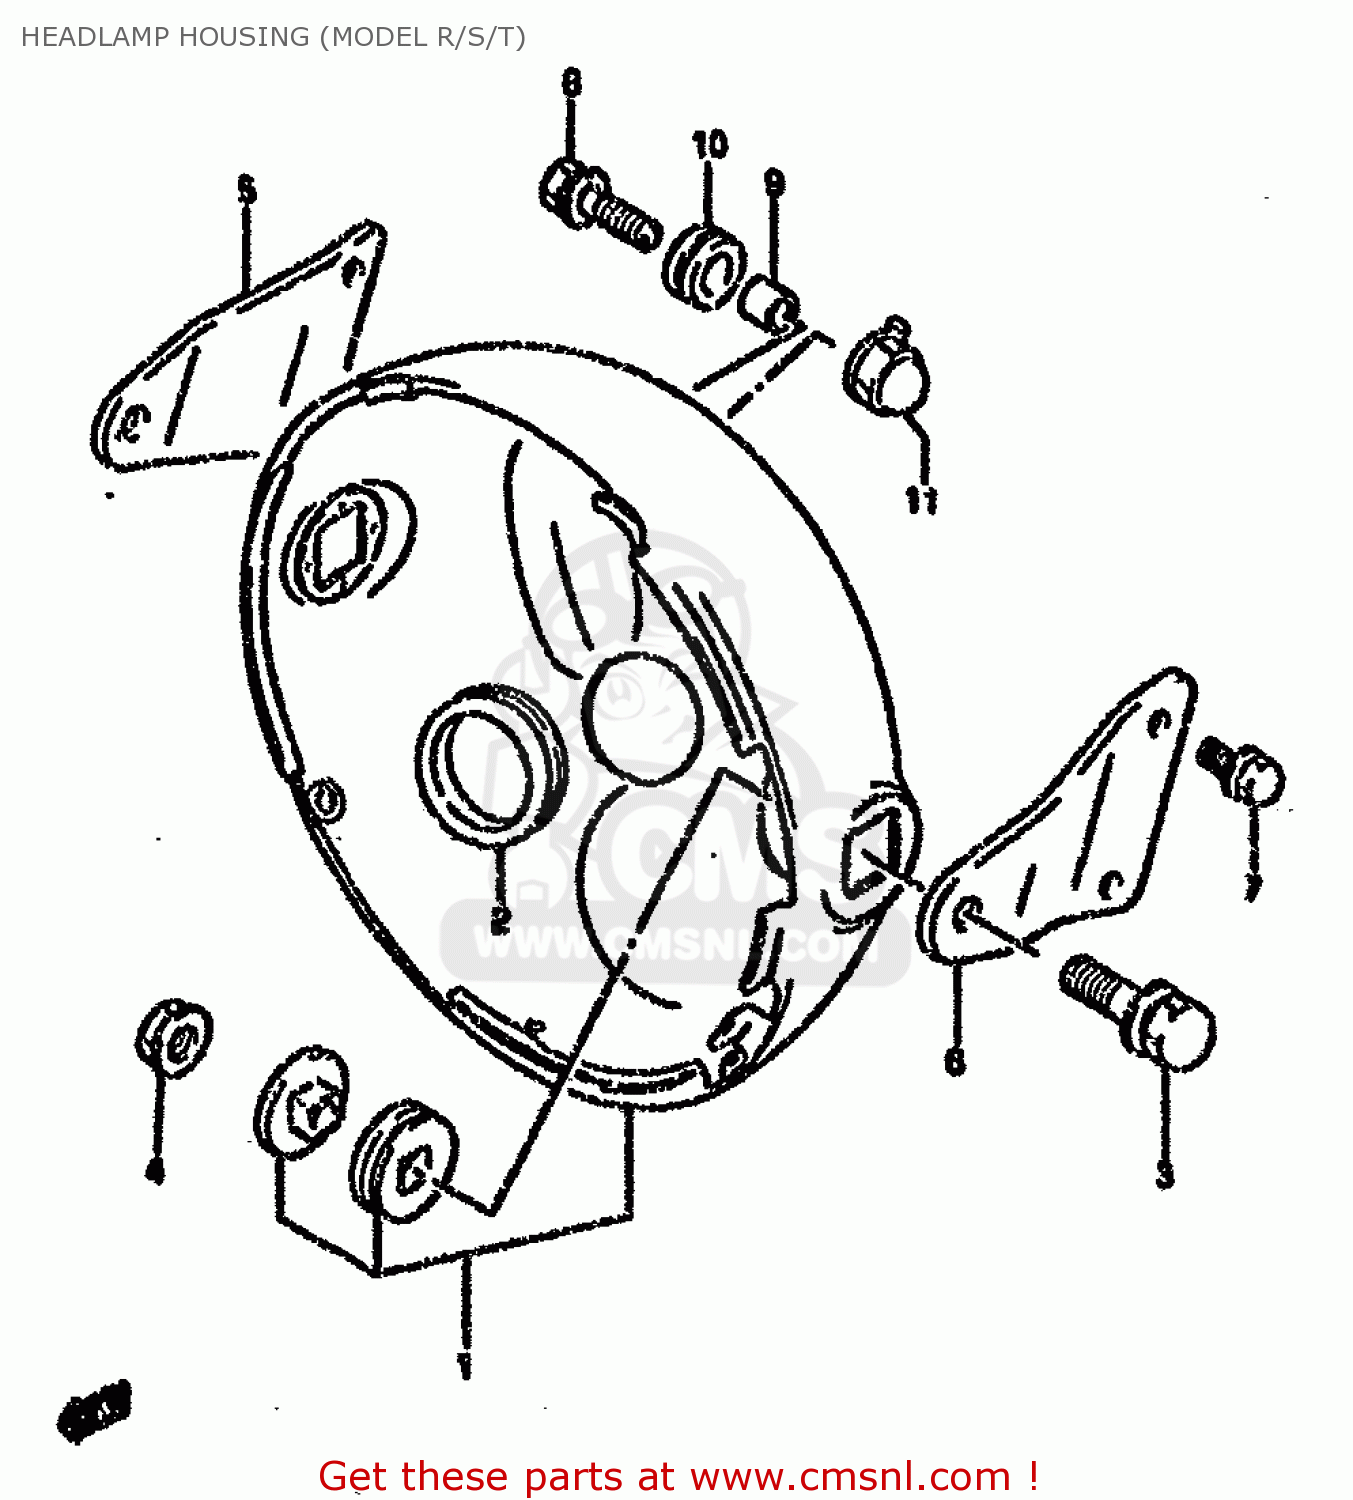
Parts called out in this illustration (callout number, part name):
1	HOUSING,HEADLAMP
2	GROMMET
3	BOLT
4	NUT
5	STAY,HEADLAMP HOUSING,R
6	STAY,HEADLAMP HOUSING,L
7	STAY,HEADLAMP HOUSING
8	BOLT
9	BOLT
10	CUSHION
11	WASHER
12	SPACER(6.5X10.5X12)
13	CUSHION
14	NUT
15	PLATE,HEADLAMP
